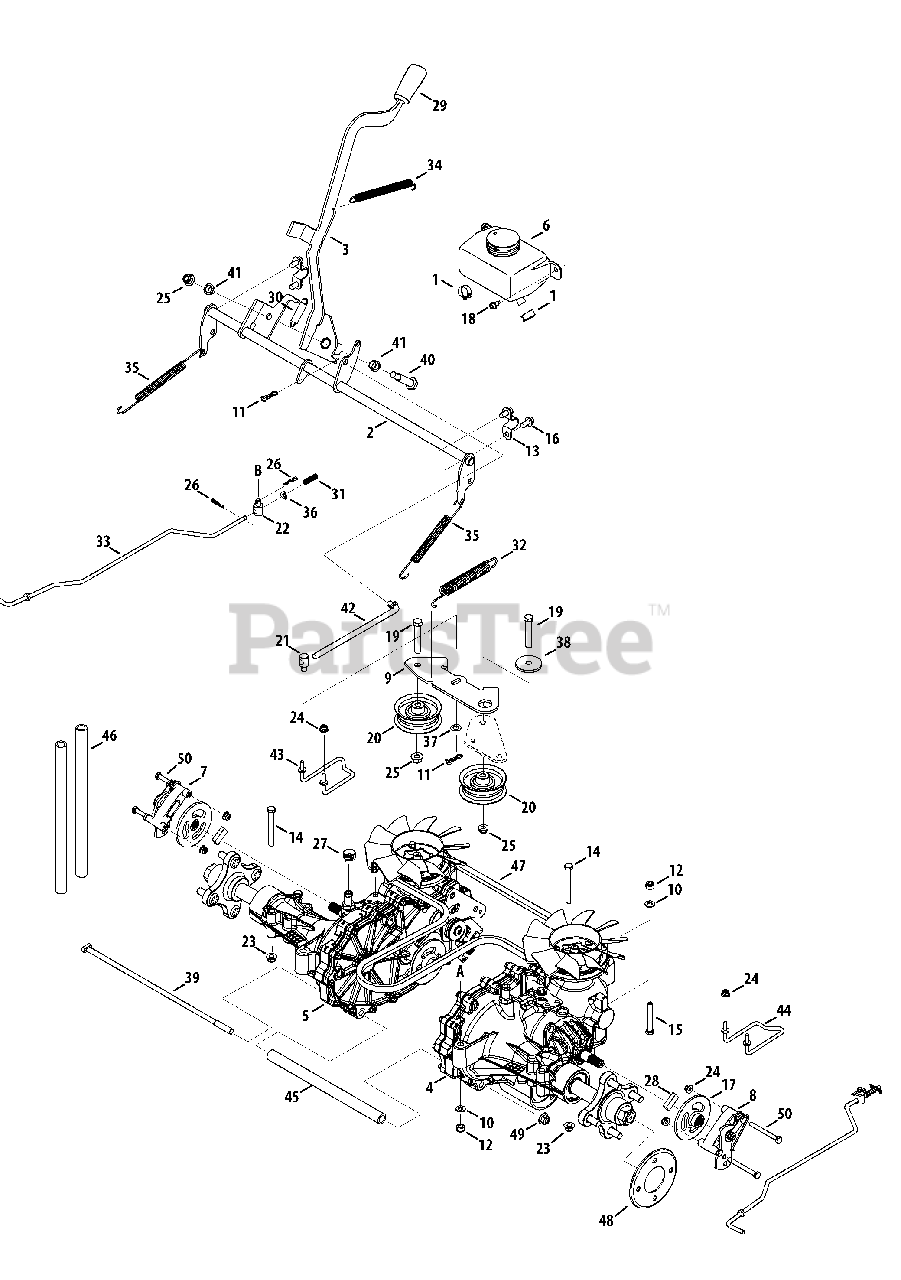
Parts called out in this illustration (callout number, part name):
1	Hose Clamp, 1/2"
2	Brake Shaft Assembly
3	Brake Handle Assembly
4	RH Transmission Assembly
5	LH Transmission Assembly
6	Expansion Tank Assembly
7	LH Brake Assembly
8	RH Brake Assembly
9	Idler Bracket
10	Flat Washer, .330 x .630 x .064
11	Bow-Tie Cotter Pin
12	Hex Lock Nut, 5/16-24
13	Shaft Mount Bracket
14	Hex Screw, 5/16-18 x 2.75
15	Hex Screw, 5/16-24 x 2.25
16	Hex Washer Screw, 5/16-18 x .750
17	Brake Disc
18	Hex Washer Screw, 1/4-20 x .500
19	Hex Screw, 3/8-16 x 2.25
20	Flat Idler Pulley, 2.75
21	Ferrule, 3/8-24 x .375
22	Ferrule, .325 x .312
23	Flange Lock Nut, 5/16-18
24	Flange Lock Nut, 1/4-20
25	Flange Lock Nut, 3/8-16
26	Cotter Pin, .072 x 1.13
27	Hose Clamp, .75 Dia. x .312
28	Brake Pad
29	Selector Handle
30	Extension Spring, .48 x 2.03
31	Compression Spring, .405 x 1.17
32	Extension Spring, .75 x 6.02
33	Transmission Bypass Lever Wire
34	Extension Spring, .50 x .6.37
35	Extension Spring, .500 x 7.0
36	Spring Washer, .317 x .625 x .020
37	Thrust Washer, .375 x .70 x .030
38	Shoulder Spacer, .884 x .190
39	Rod, .405 x 14.00
40	Shoulder Screw, .498 x 1.635
41	Flange Bearing, .500 x .34
42	Disenage Brake Rod
43	LH Rod Keeper
44	RH Rod Keeper
45	Transmission Spacer, 10.5
46	Fuel Hose, 1/2 x 12.00
48	Reinforcement Plate
49	Flange Lock Nut, 7/16-20
50	Hex Screw, 1/4-20 x 2.50
